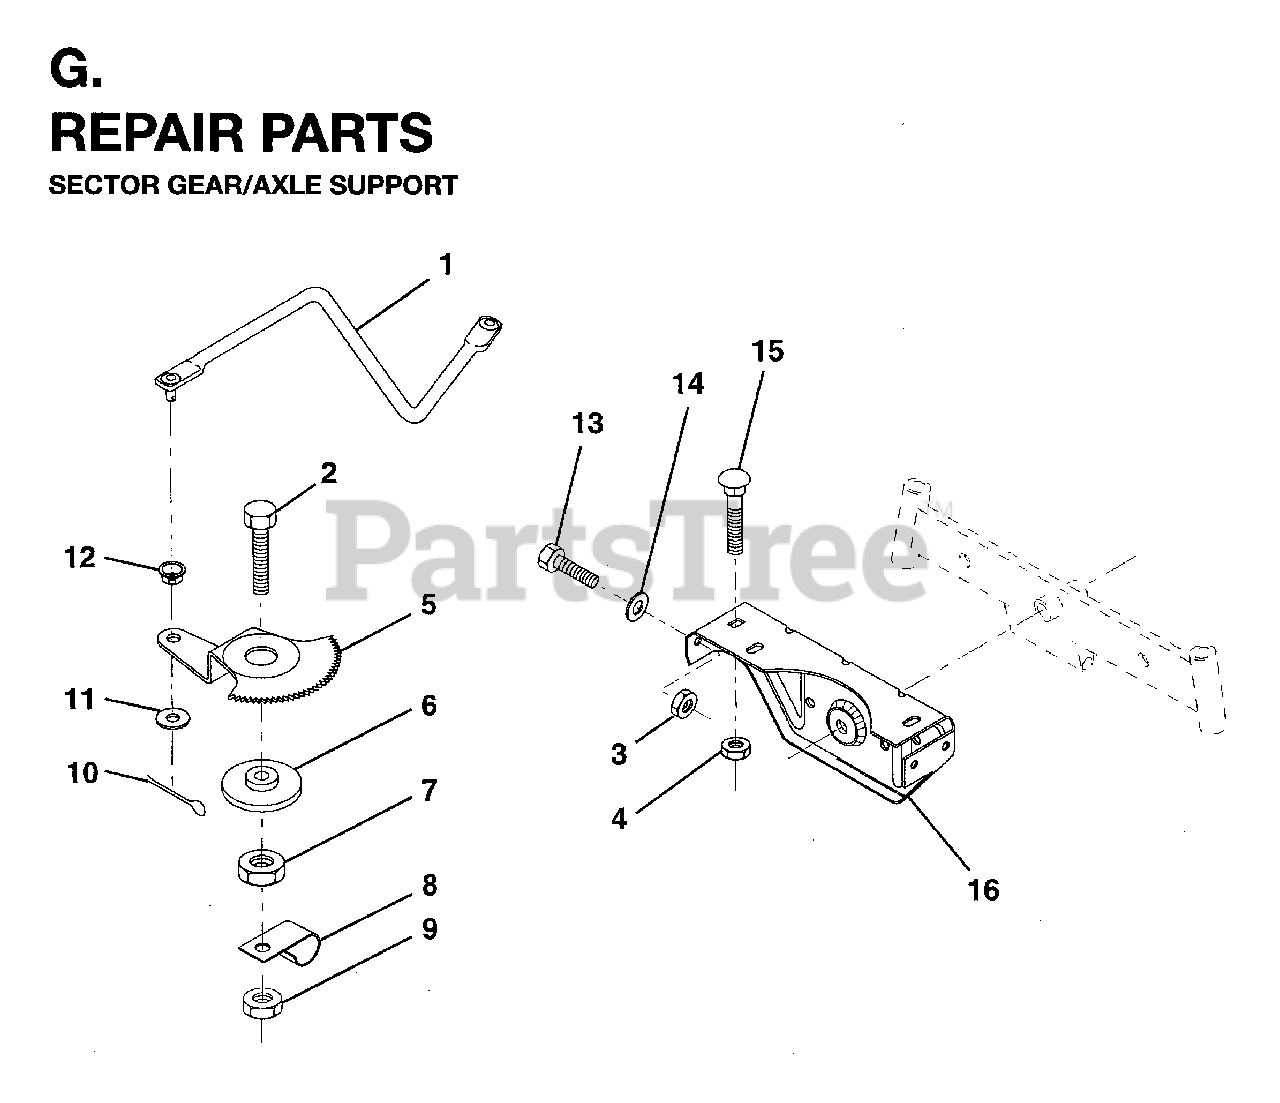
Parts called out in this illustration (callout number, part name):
1	LINK DRAG
3	LOCKNUT
4	LOCKNUT
5	GEAR SECTOR
7	NUT LTV
8	CLIP INSULATOR
9	NUT LTV
10	COTTER PIN
11	WASHER
12	BUSHING.DRAGLINK
13	BOLT
14	WASHER - 25X8.5X2.3
16	SUPPORT/AXLE FRONT
